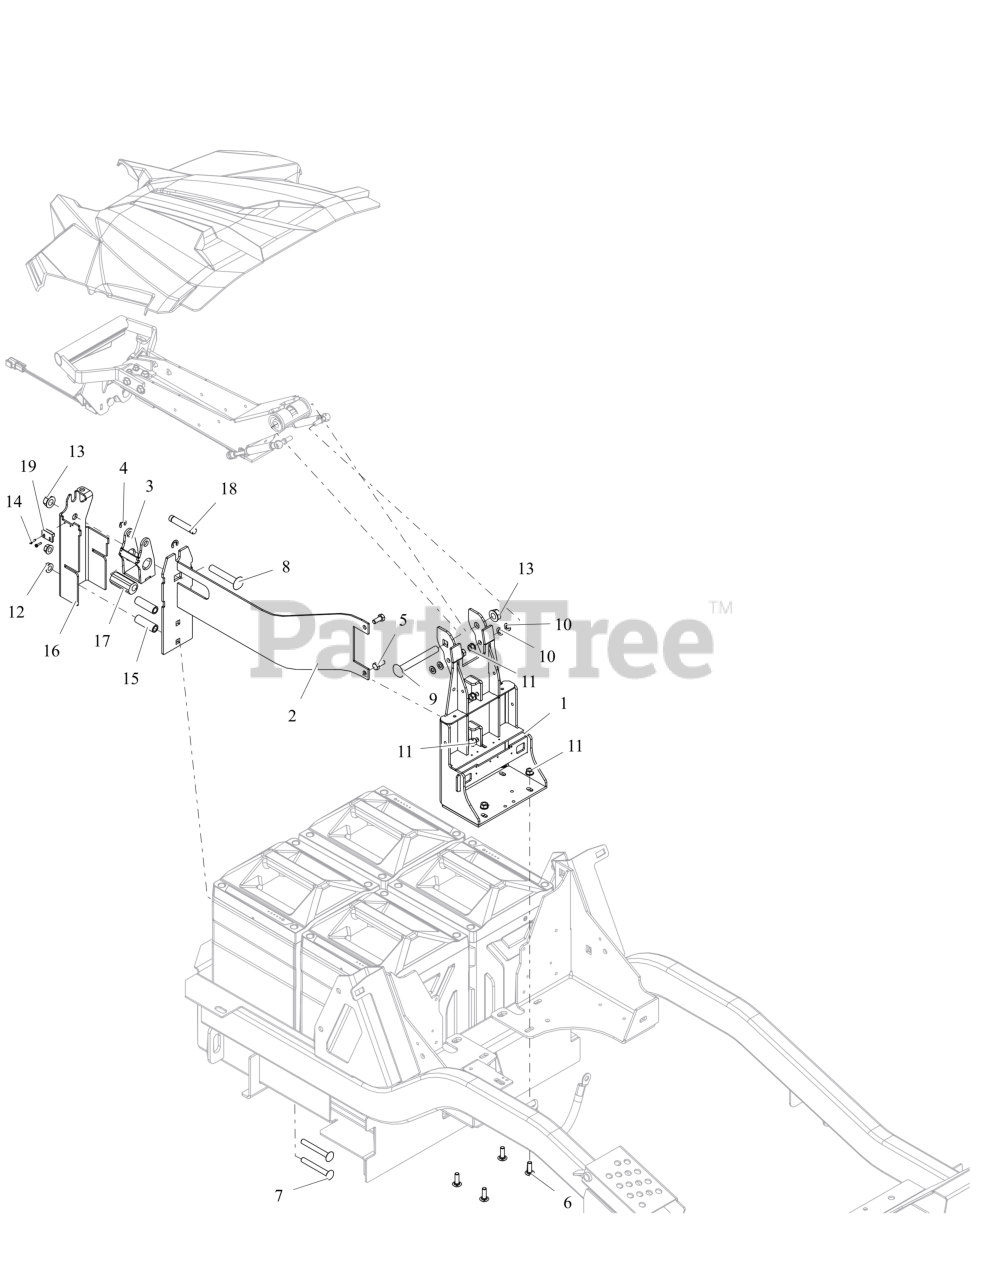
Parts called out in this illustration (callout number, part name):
1	WLDMT, BATTERY HOLDDOWN PIVOT (ORANGE)
2	WLDMT, ECCENTRIC MTG (ORANGE)
3	WLDMT, ECCENTRIC (BLACK)
4	RG-RTNG-EXT .438X.035
5	BLT,HEX .31-18X.75 G5 ZCC
6	BLT,RHSSN .31-18X1.00 G5 ZCC
7	BTL,RHSSN .375-16 X 3 G5 ZCC
8	BTL,RHSSN .500-13 X 3 G5 ZCC
9	BTL,RHSSN .500-13 X 4.25 G5 ZCC
10	WSHR,FLT .323X.625X.062 ZCC
11	NUT,LK-CTR-FLG .31-18 GF ZCC
12	NUT-LK-CTR-FLG .375-16 GF ZCC
13	NUT-LK-CTR-FLG .500-13 GG ZCC
14	SCR-TAP #4-40x.50 HWH ZCC
15	SPCR, LATCH BRKT (BLACK)
16	BRKT, ECCENTRIC MTG (ORANGE)
17	ECCENTRIC, HOOD LATCH
18	ROD, LATCHING
19	SWITCH, MAGNET (NO WIRE)
